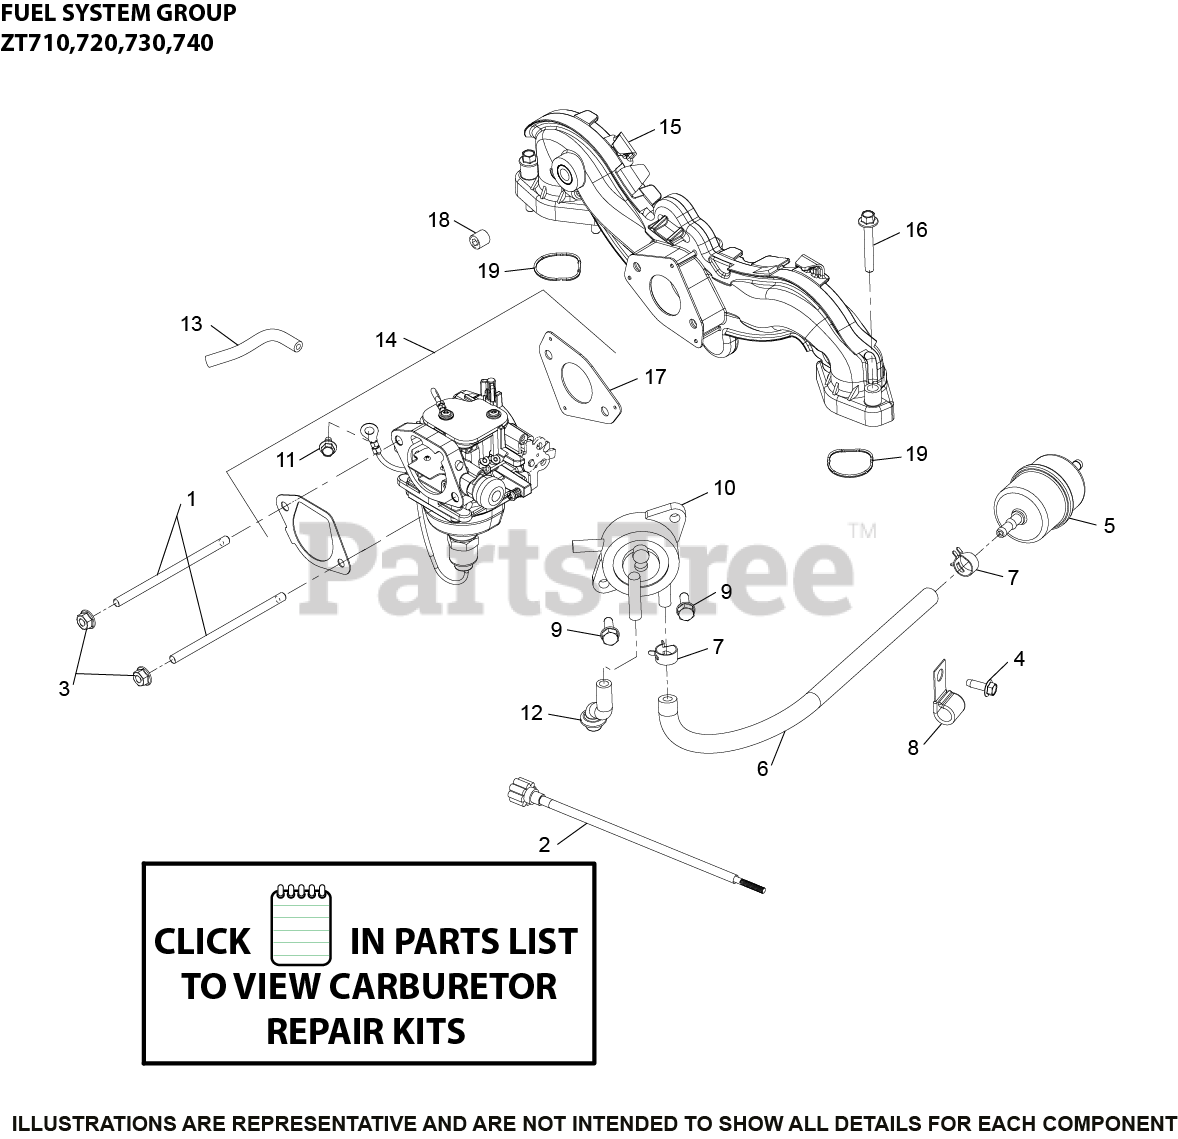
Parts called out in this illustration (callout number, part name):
3	NUT, FLG M6X1.0
4	SCREW, THREAD FORMING
5	FILTER, FUEL
6	HOSE,LW PERM.FUEL 24.00"-USE 25 111 81-S
7	CLAMP SPRING HOSE
8	CLIP, CABLE
9	SCREW, TAP M6X1.7X18
10	PUMP, FUEL
11	SCREW, THREAD FORMING
12	HOSE, PULSE PUMP
14	KIT, CARBURETOR
15	KIT, INTAKE MANIFOLD USE 24 164 266-S
16	SCREW, FLG M6X1.0X40
17	GASKET, CARBURETOR
18	PLUG, CTSK PIPE 1/8"
19	O-RING, INTAKE PORT
